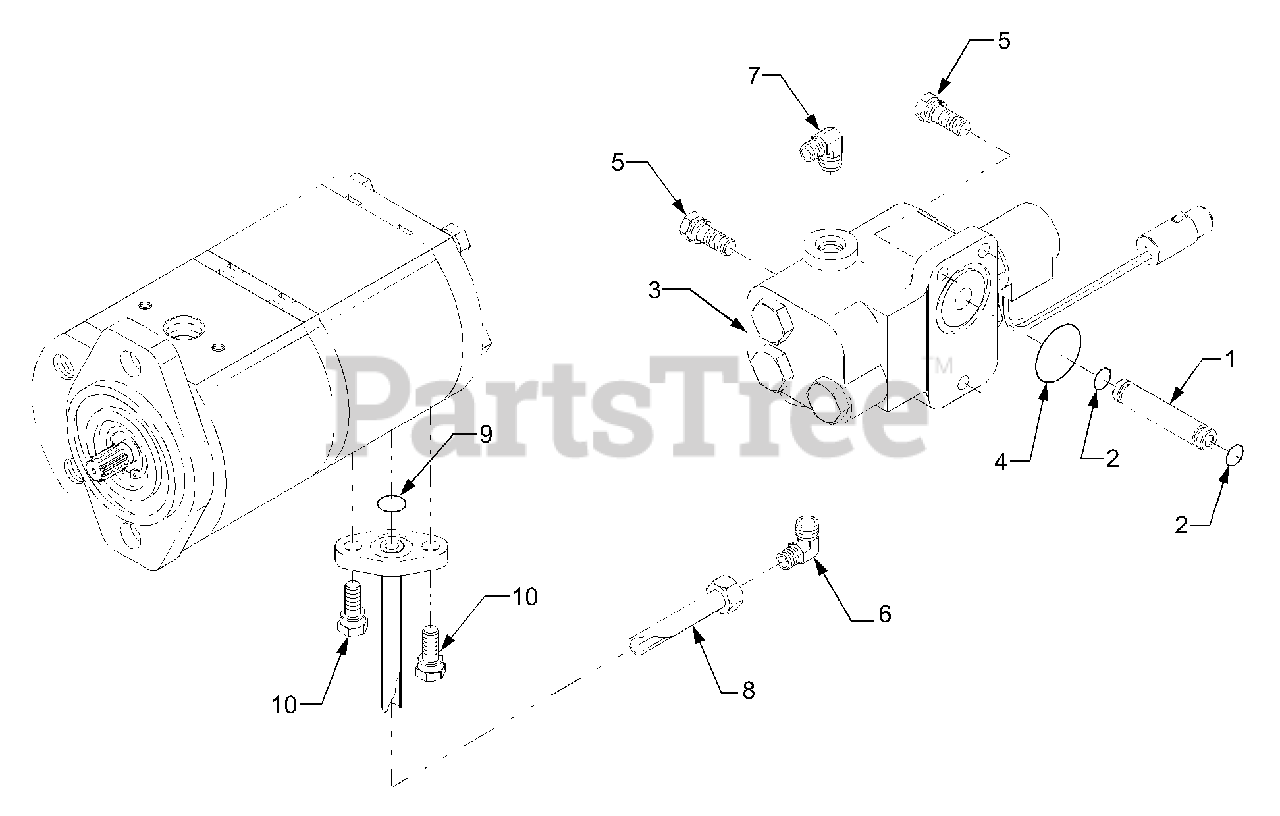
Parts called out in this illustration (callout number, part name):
1	Pipe, Connector
3	Modulater Valve Ass'y
8	Pipe, PTO Hydraulic
